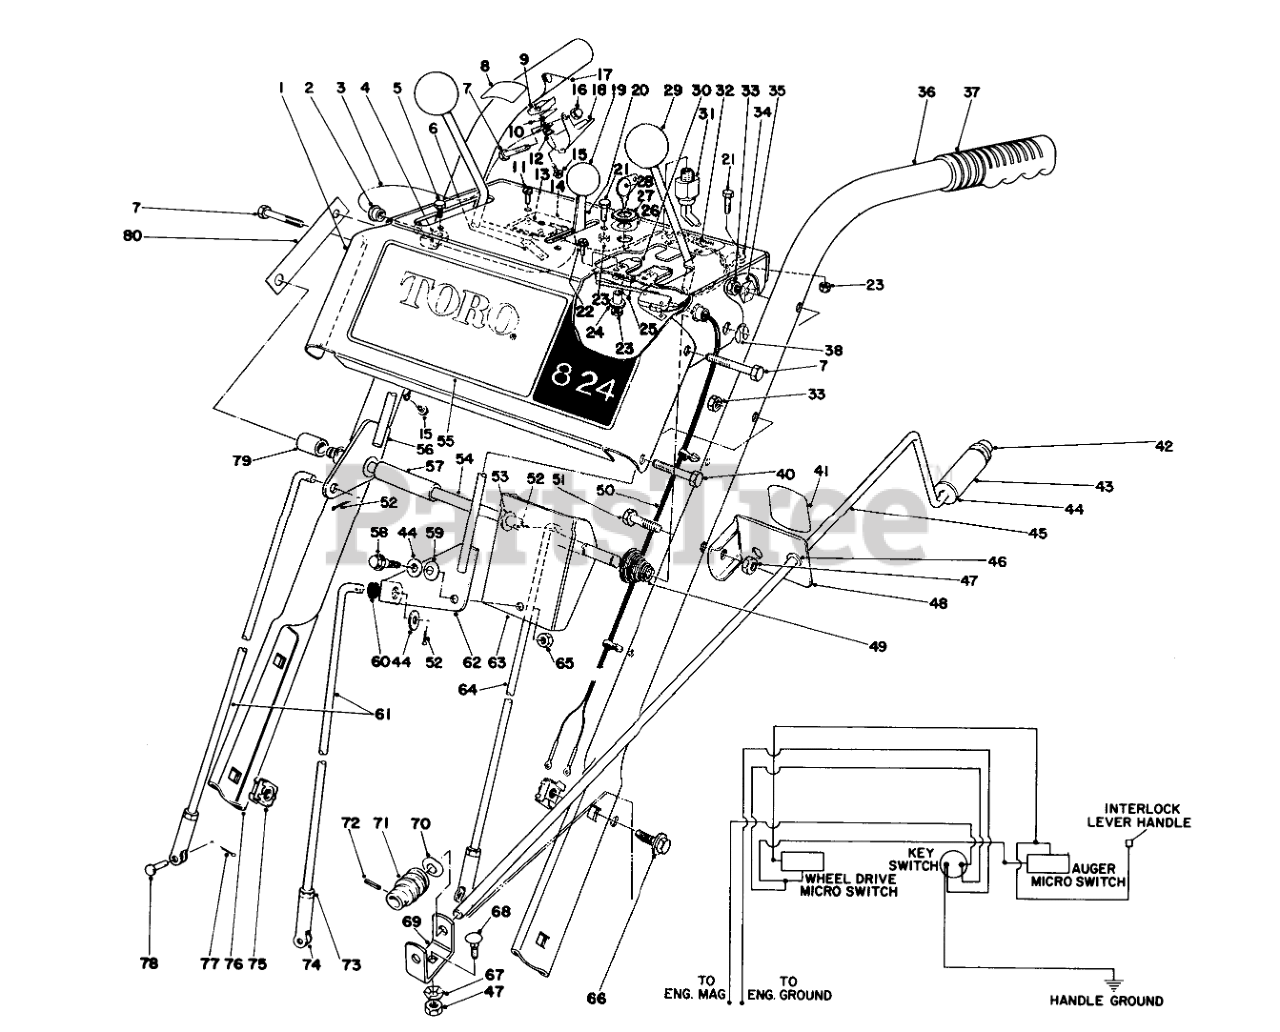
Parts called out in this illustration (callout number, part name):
1	Escutcheon
2	Snap Bushing
3	Wire Assembly
4	PLASTIC CLIP
5	SCREW
6	NUT-SPEED
7	SCREW-HH
8	INTERLOCK DECAL
9	Insulator
10	INTERLOCK CONTACT
11	SCREW-SPH
12	WASHER INSULATOR
13	MICRO SWITCH
14	SWITCH MTG PAD
15	SCREW
16	NUT-CAP
17	INTERLOCK SPRING
18	SAFETY INTRLOCK LEVER
19	CONTROL KNOB
20	THROTTLE CONTROL
21	HEX HEAD SEMS 10-24X1/2
22	SCREW-SRH
23	Nut
24	INTERLOCK SPACER
25	INTERLOCK SPRING
26	WASHER-TOOTH, INTERNAL
27	NUT-HH
28	Key
30	Slide Interlock
31	SWITCH-ON / OFF
32	INSTRUCTION DECAL
33	NUT-LOCK, CONE
34	CABLE CLAMP
35	Washer
36	LEFT HANDLE
37	Grip Handle
38	RING-CLIP
40	SCREW-HH
41	CHUTE DECAL
42	RETAINER-PUSH ON
43	CHUTE CONTROL GRIP
44	WASHER-FLAT
45	CHUTE CONTROL ROD
46	Bushing
47	NUT-LOCK, NI
48	Chute Control Rod Mounting (Incl. Ref. #41 & 46)
49	CONICAL SPRING
50	Wire Harness Interlock
51	SCREW-HH
52	PIN-COTTER
53	WASHER-FLAT
54	PIVOT ROD
55	ESCUTCHEON DECAL
56	LEVER WA
57	SHIFT LEVER SPACER
58	SHOULDER SCREW
59	7/16 SPRING WASHER
60	GROMMET-RUBBER
61	SPEED SELECTOR ROD
62	SHIFT LEVER WA
63	SHIFT BRACKET
64	TRACTION CONTROL ROD
65	NUT-LOCK, CONE
66	SCREW-HHF
67	WASHER-LOCK
68	BOLT-CARR
69	WORM BRACKET
70	WASHER-SPRING
71	GEAR-WORM, CHUTE
72	PIN-SPRING
73	NUT-HJ
74	CLEVIS
75	Retained Nut
76	RIGHT HANDLE
77	PIN-COTTER
78	PIN-CLEVIS
79	AUGER LEVER SPACER
80	ESCUTCHEON SUPT STRAP
